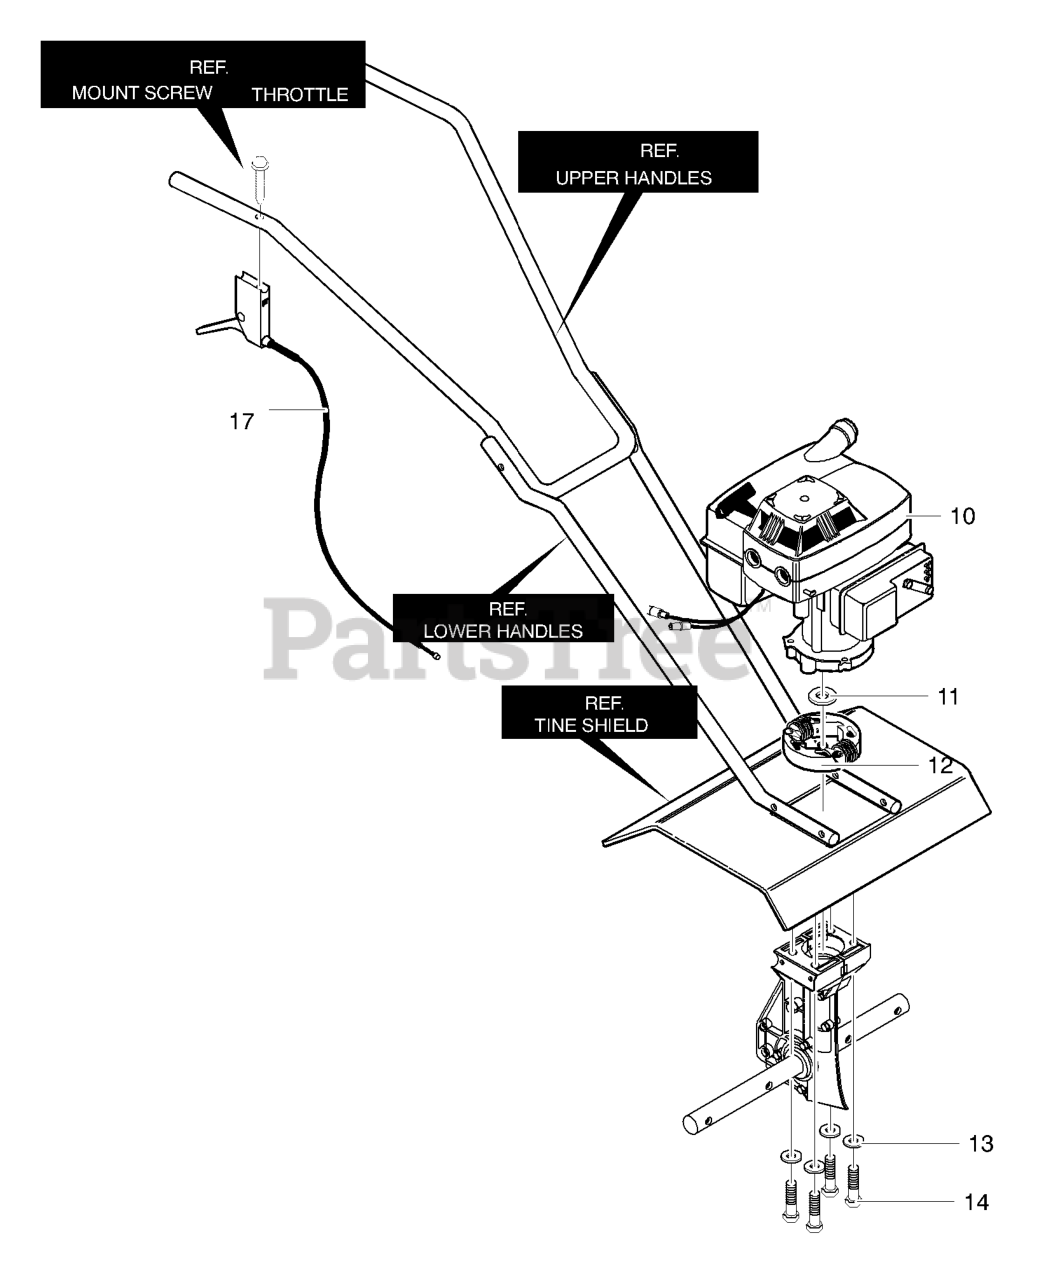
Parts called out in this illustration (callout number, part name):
10	Engine 2.0 HP
11	Flat washer
13	Washer, Regsptlk
14	Screw
17	Cable, Throttle
